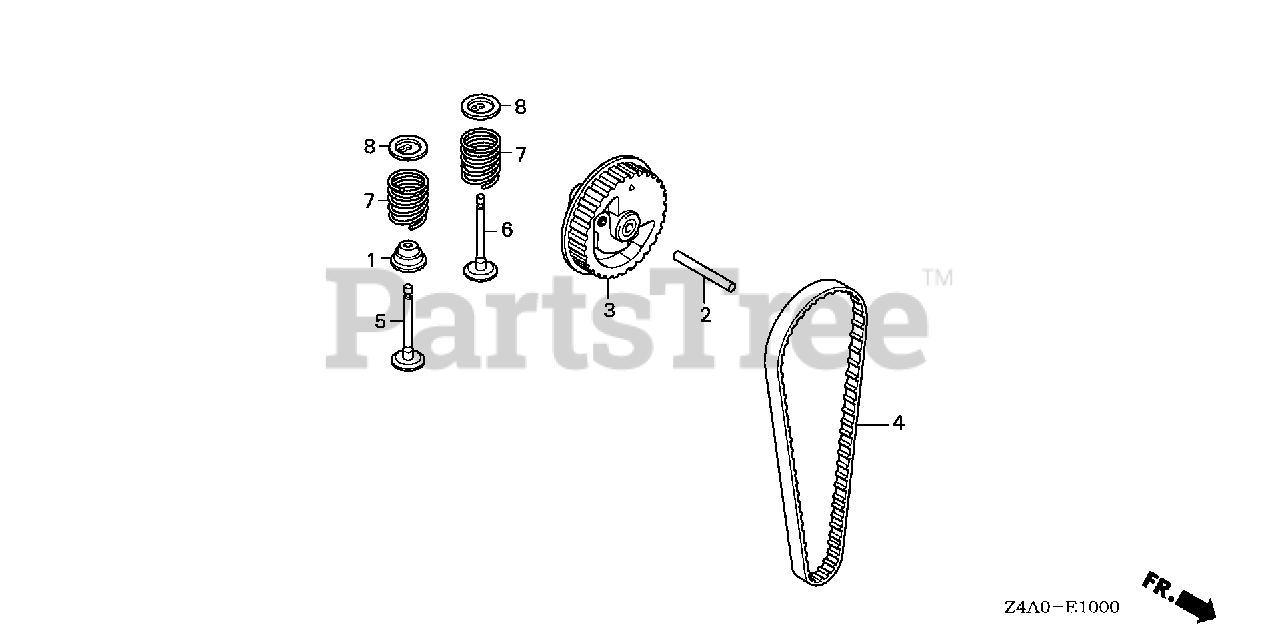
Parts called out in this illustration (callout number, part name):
1	SEAL, VALVE STEM
2	ROLLER (4X29.8)
3	PULLEY, CAMSHAFT
4	BELT, TIMING (71ZU5 G-310)
5	VALVE, IN. (HI)
6	VALVE, EX. (HE)
6	VALVE, EX. (EE)
7	SPRING, VALVE
8	RETAINER, VALVE SPRING
